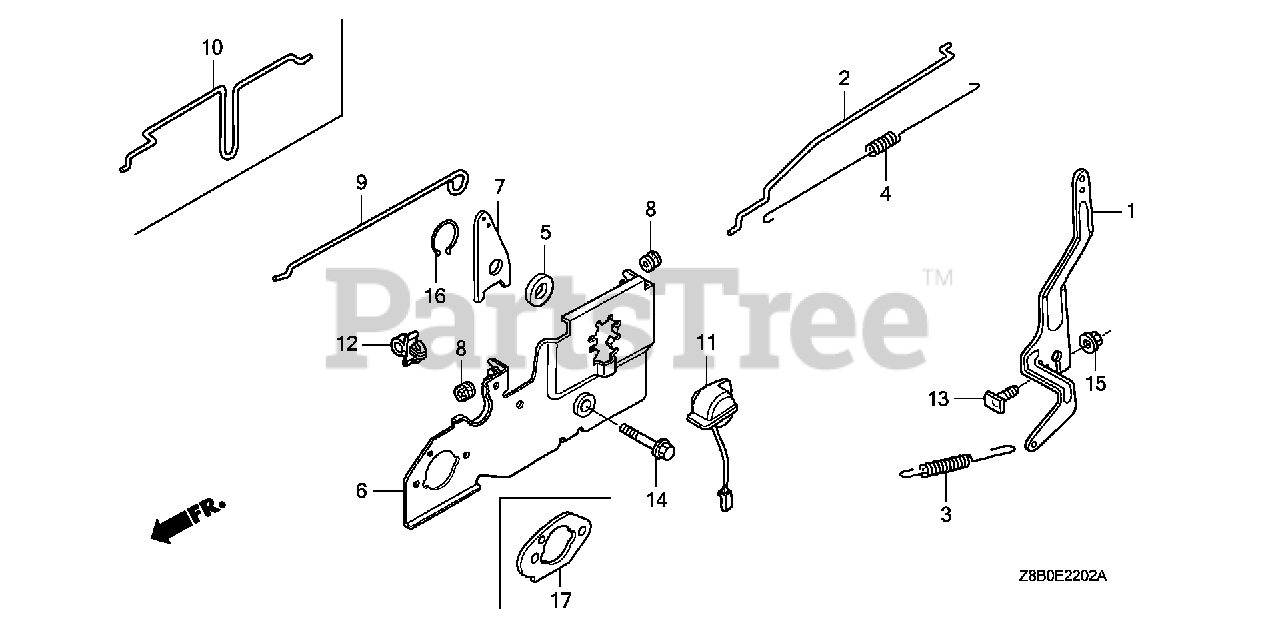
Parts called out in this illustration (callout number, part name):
1	ARM, GOVERNOR
2	ROD, GOVERNOR
3	SPRING, GOVERNOR
4	SPRING, THROTTLE RETURN
5	SPACER, CONTROL LEVER
6	BASE, CONTROL
7	LEVER, CHOKE
8	GROMMET, CHOKE ROD
10	ROD, CHOKE
13	BOLT, GOVERNOR ARM
14	BOLT, FLANGE (6X45) (CT200)
15	NUT, FLANGE (6MM)
16	CIRCLIP (OUTER) (14MM)
